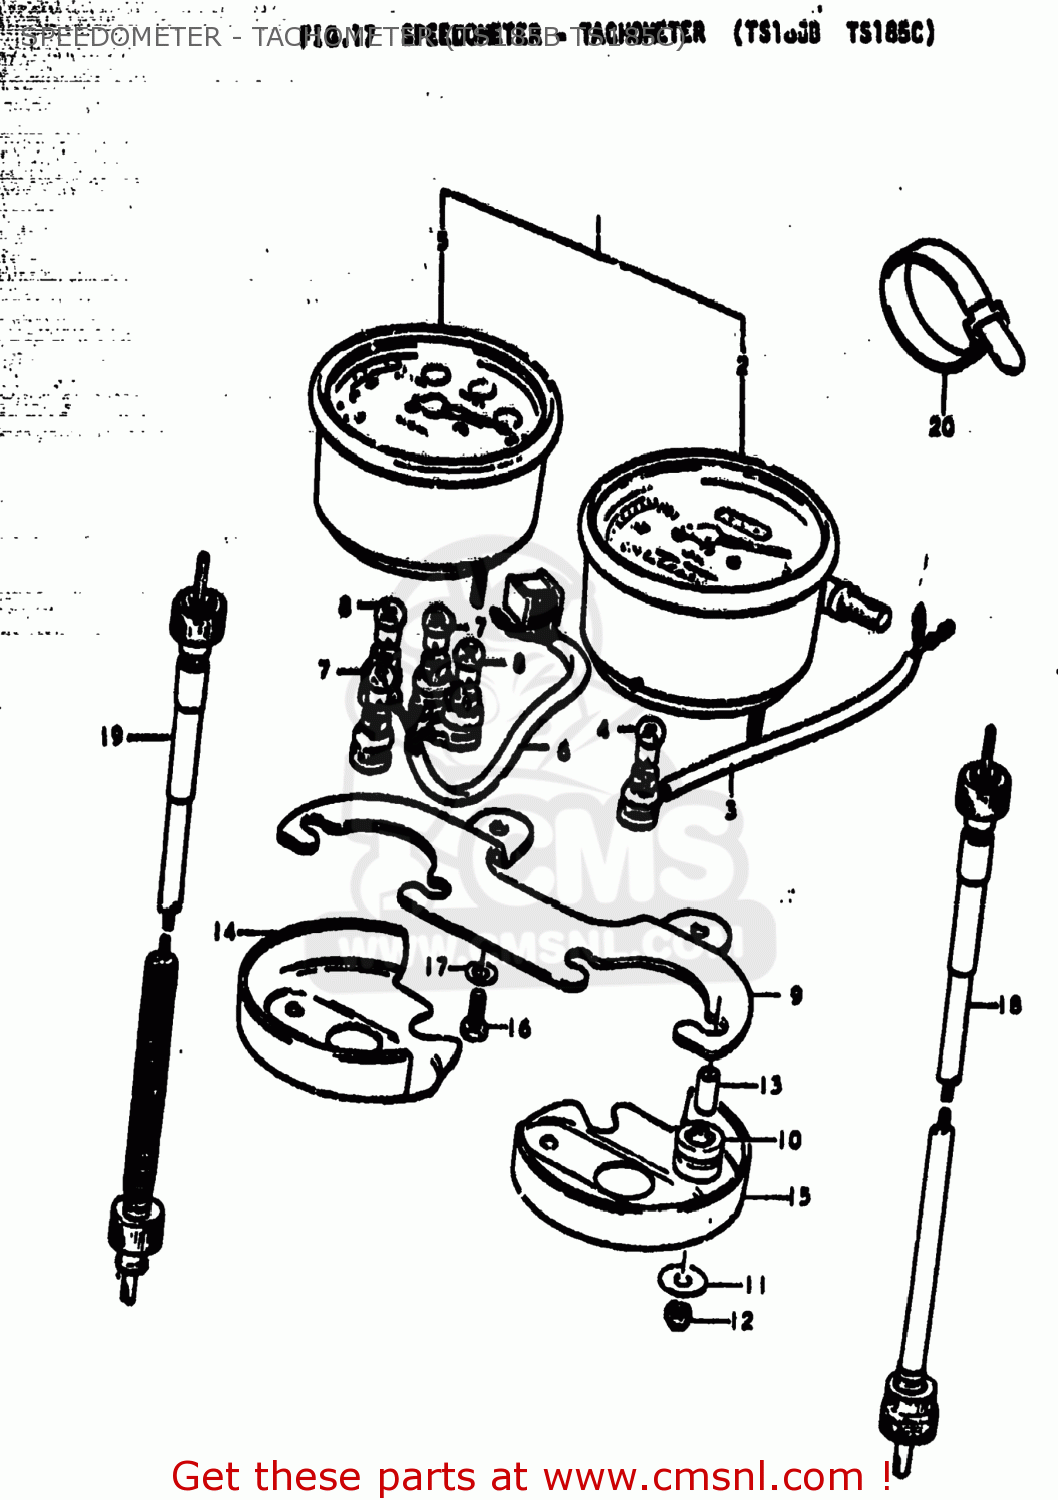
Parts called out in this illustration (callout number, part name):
1	SPEEDOMETER ASSEMBLY
2	SPEEDOMETER ASSEMBLY
3	SOCKET,SPEEDOMETER
4	BULB(6V/3W)
5	METER,TACHOMETER
6	SOCKET,TACHOMETER
7	BULB(6V/3W)
8	BULB(6V1.7W,STANLEY,A61A)
9	BRACKET,COMBINATION METER
10	CUSHION,METER
11	WASHER,METER
12	NUT
13	SPACER,METER
14	COVER,METER,UNDER
15	BRACKET,SPEEDOMETER,UNDER
16	BOLT, UPPER
17	WASHER 6MM
18	CABLE ASSEMBLY,SPEEDOMETER
19	CABLE ASSEMBLY,TACHOMETER
20	CLAMP
